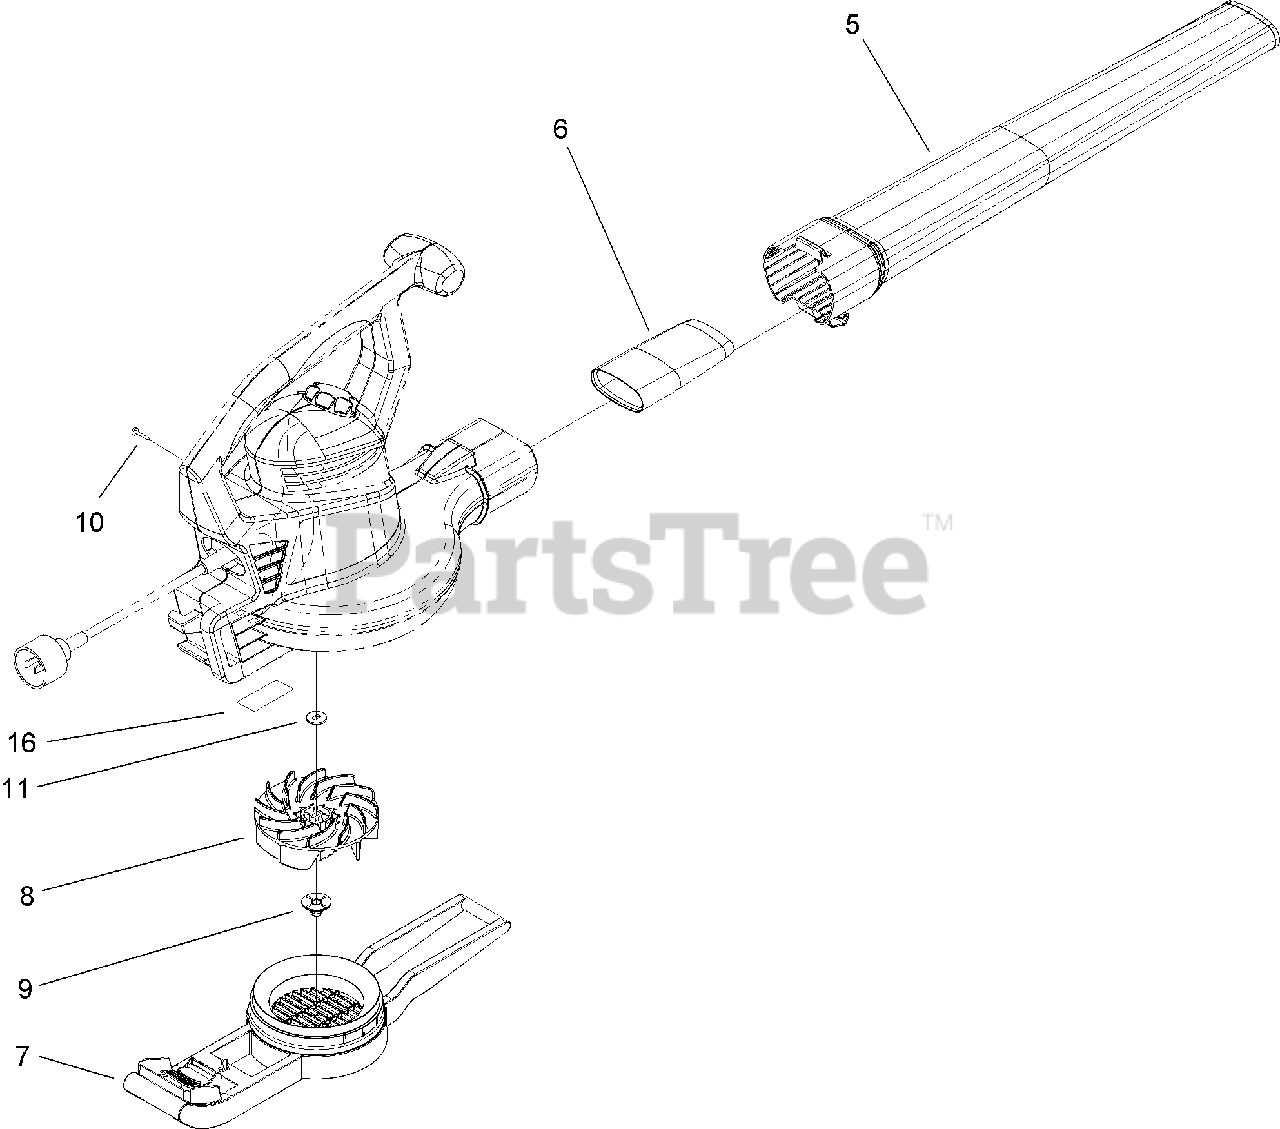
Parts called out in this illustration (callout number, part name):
5	TUBE-BLOWER
6	TUBE-INSERT
7	COVER-INLET
8	Impeller-Magnesium
9	NUT-HEX,
10	SCREW-PPH
16	DECAL-CAUTION
